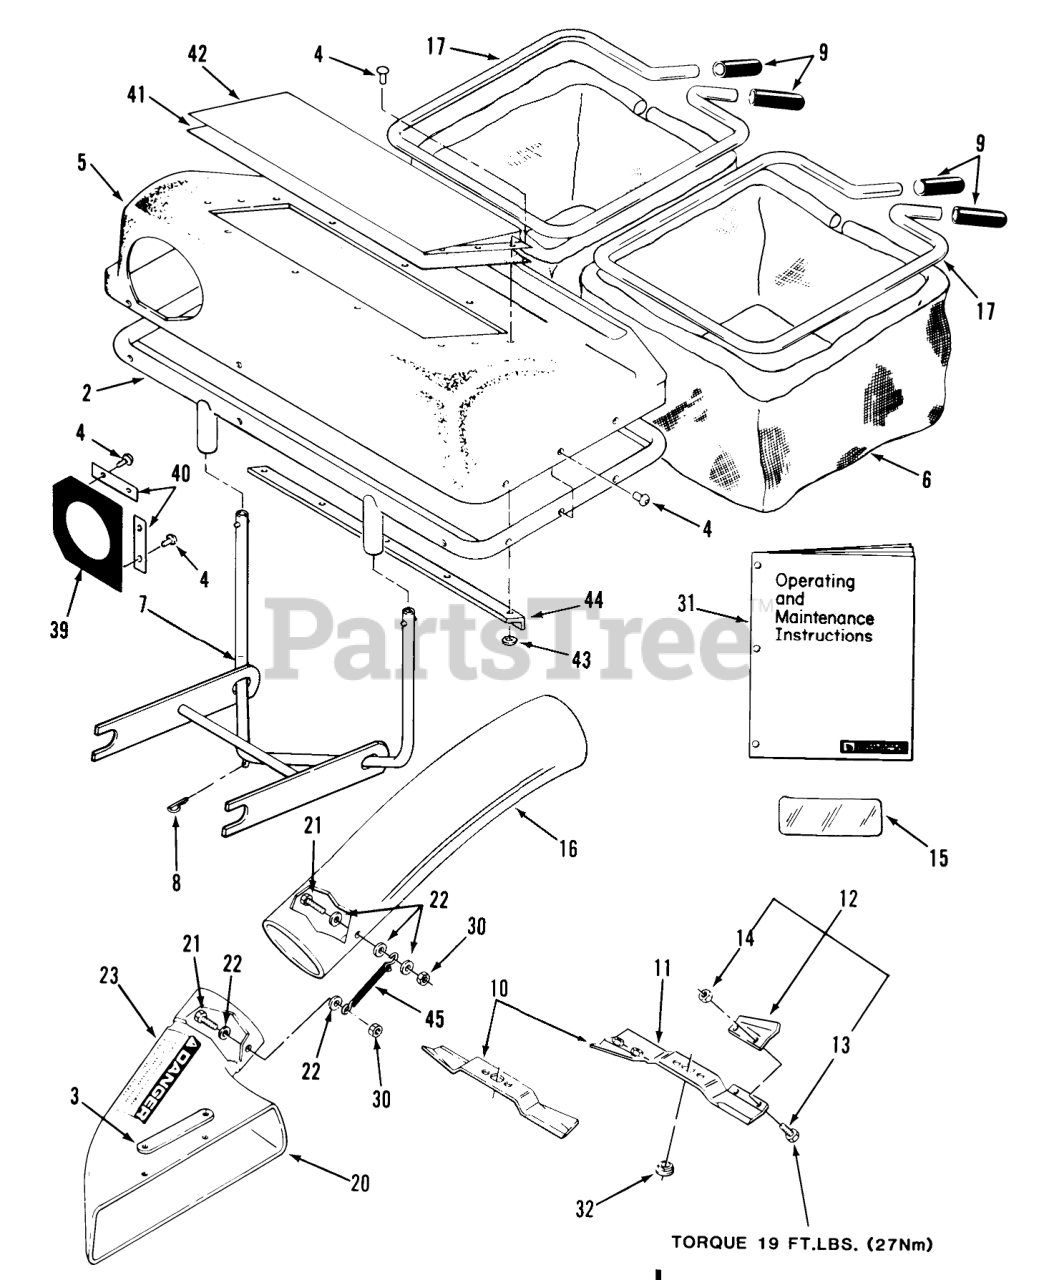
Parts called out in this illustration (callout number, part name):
2	Frame
3	PLATE-ELBOW B
4	RIVET-BLIND
5	TOP-BAG'R (37")
6	BAG-BLACK(37"TWIN)
7	ASS'Y-QUICK ATTAC B
8	Hairpin Cotter
9	GRIP
10	Blade Kit (includes LH blade, RH blade with tabs & hardware) 07-07BK01 Only
10	Blade Kit (includes LH blade, RH blade with tabs & hardware) 07-07BK02 Only
11	High Lift Blade (includes item 12) RH 07-07BK01
11	High Lift Blade (includes item 12) RH 07-07BK02
12	Lift Tab Kit (includes items 13 & 14)
13	BOLT 5/16-18X5/8
14	NUT-LOCK 5/16-18
15	DECAL-OVERLAY
16	Tube (includes items 21, 22 & 30)
17	FRAME BAG B
20	Elbow (includes items 21, 22, 23 & 30)
21	Bolt
23	DECAL-DANGER
30	Nut
31	Operating and Maintenance Instructions
32	SPACER BLADE
39	SEAL-CHUTE
40	STRAP-SEAL
41	Top Screen
42	Screen Cover
43	Washer
44	Top Stiffener
45	STRAP
